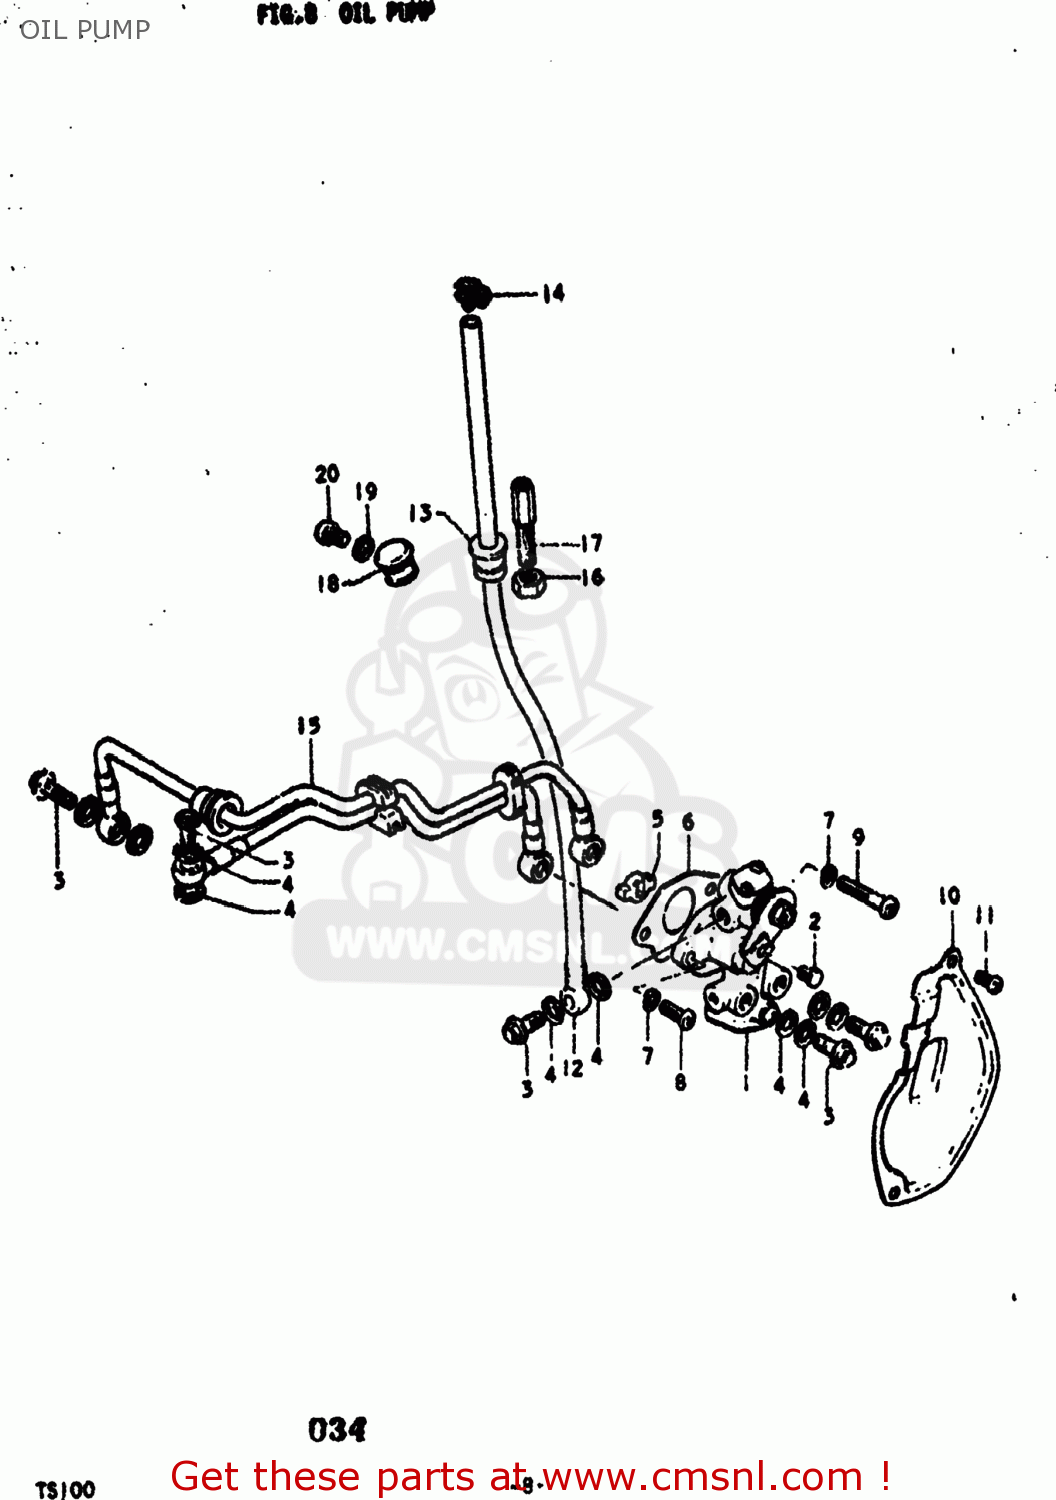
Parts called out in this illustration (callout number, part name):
1	PUMP ASSEMBLY,OIL
2	TERMINAL,CABLE
3	UNION BOLT
4	GASKET (NAS)
5	PIECE,OIL PUMP DRIVE
6	GASKET,OIL PUMP (MCA)
7	LOCK WASHER
8	SCREW
9	SCREW
10	CAP,OIL PUMP INSPECTION
11	SCREW
12	HOSE,OIL NO.1
13	BUSHING
14	CLAMP
15	HOSE,OIL NO.2
16	NUT
17	BOLT
18	Plug
19	WASHER
20	SCREW
